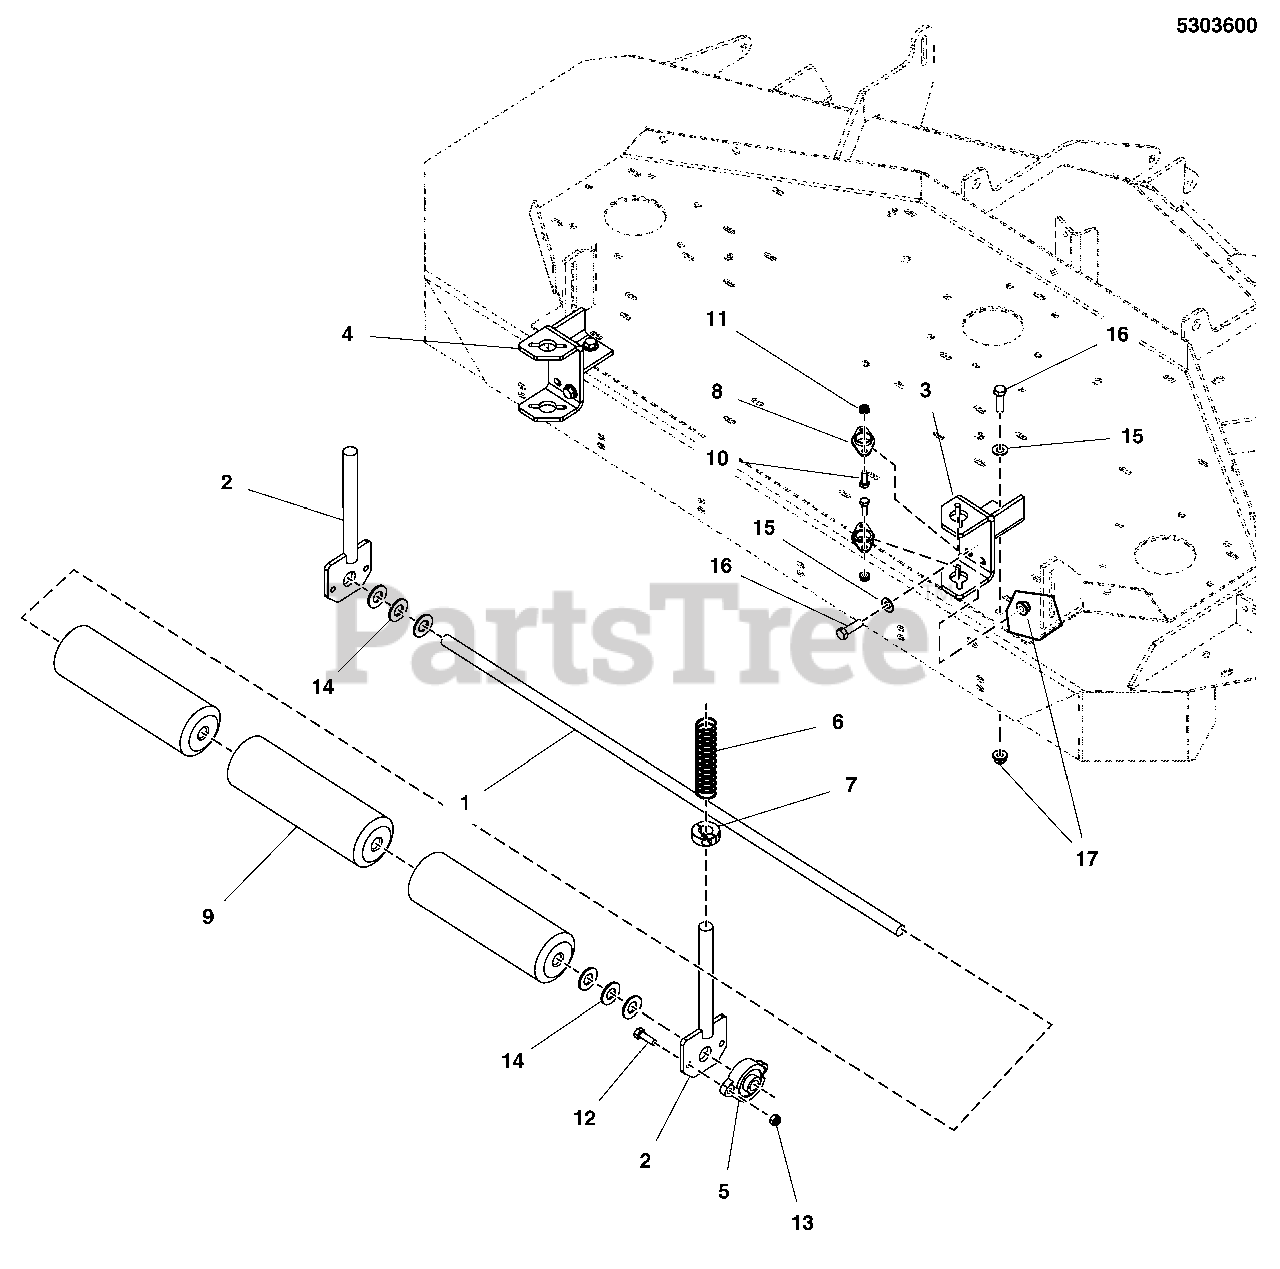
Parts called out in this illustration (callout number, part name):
1	SHAFT, 5/8 X 34.25
2	WELD, ROLLER SLIDE - BLK
3	WELD, ROLLER MT, RH - BLK
4	WELD, ROLLER MT, LH - BLK
5	BEARING-FLANGE, 5/8
6	SPRING-COMPRESSION
7	COLLAR, 3/4 DOUBLE SPLIT
8	BUSHING, FLANGE, GFL - 20
9	ROLLER, DECK
10	BOLT, 1/4-20 X 3/4 GD5 YZ
11	NUT, 1/4-20 HEX NYLOCK FLANGE
12	BOLT, 5/16-18 X 1 GD5 YZ
13	NUT, 5/16-18 HEX NYLON LOCK
14	WASHER, 5/8 SAE
15	WASHER, 3/8 SAE
16	BOLT, 3/8-16 X 1-1/4 GD5
17	NUT, 3/8-16 HEX NYLOCK FLANGE
